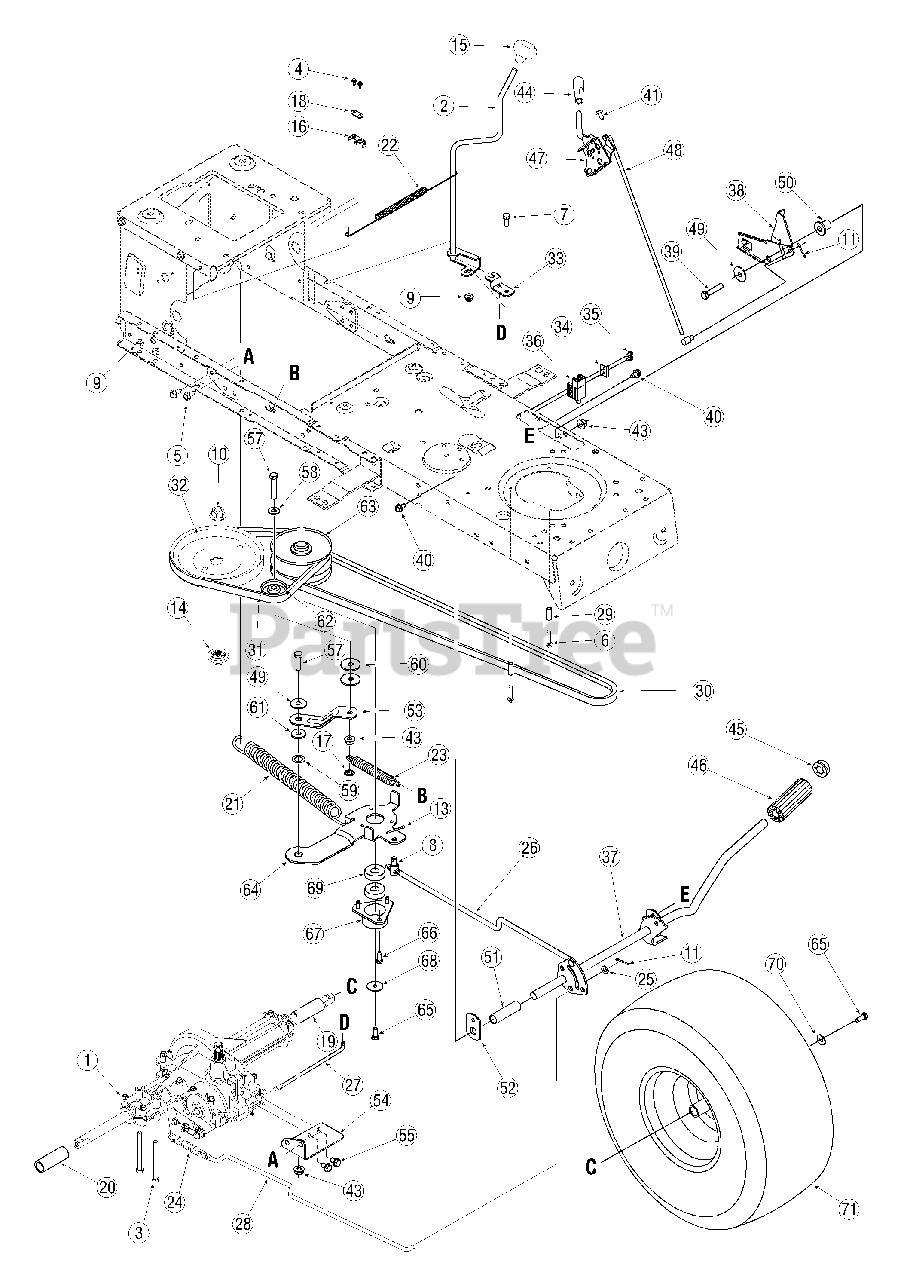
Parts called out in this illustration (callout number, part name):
1	Transmission Assembly
2	Lever Assembly, Shift
3	Screw, 5/16-18, 2.75, Gr5
4	Screw, #8-18, 0.500
5	Screw, 5/16-12, 0.750
6	Screw, 1/4-20, 1.250
7	Screw, 5/16-18, .75, Gr5
8	Ferrule, 3/8-24 x .375 Dia.
9	Nut, Flange Lock, 5/16-18, Gr F, Nylon
10	Nut, Flange, 9/16-18, Gr2
11	Pin, Cotter, 3/32, 1.0
12	Cotter Pin, Internal .125 Dia
13	Pin, Cotter, 1/8 x 1.25
14	Hub, Pulley, 5/8 Spline
15	Knob, Shift
16	Spring Switch, Short
17	Speed Nut, 3/8 (Push-on)
18	Plate, Insulator Nut
19	Sleeve, .758 x .821 x 3.3125
20	Sleeve, .758 x .821 x 2.4375
21	Spring, Extension, 1.15 OD x 7.90
22	Spring, Extension, .50 OD x 12.0
23	Spring, Extension, .78 OD x 3.5
24	Spring, Extension, .59 OD x 4.00
25	Washer, Flat, .330 x .630 x .0635
26	Control Rod, Variable Speed
27	Rod, Shift
28	Rod, Brake
29	Spacer, .260 x .372 x 1.030
30	Belt
31	Belt
32	Pulley, V-Type, 7.25 Dia
33	Shift Bracket, Adjustable
34	Plate, Switch
35	Screw, #10-16, 0.500
36	Switch, Interlock
39	Screw, 3/8-16, 1.75, Gr5
40	Screw, 5/16-18, 0.500
41	Screw, 1/4-20, 0.625
42	Adjustment Ferrule 1/4-20
43	Nut, Flange Lock, 3/8-16, Gr F, Nylon
44	Knob, Speed Control
45	Push Cap, 5/8
46	Pad, Foot, 4.0
47	Shift Lever, 7-Speed
48	Control Rod, Speed Selector
49	Spacer, Shoulder, .38 ID x 50 OD x.15
50	Spacer, Flange, .390 x .671 x .95
51	Spacer, .640 ID x .76 OD x 2.63
52	Support Bracket, Pedal
53	Bracket, Idler
54	Torque Bracket, Transmission
55	Screw, 5/16-18, 0.625
56	Screw, 3/8-16, 1.25, Gr5
57	Screw, 3/8-16, 2.00, Gr5
58	Washer, Flat, .406 x .875 x .059
59	Washer, Flat, .63 x 1.00 x .015
60	Washer, Flat, .406 x 1.5 x .105
61	Spacer, Shoulder, .625 ID x .169
62	Pulley, Flat Idler, 2.0 OD
63	Pulley Ass'y, Variable Speed, 4.75 OD
64	Bracket Ass'y, Variable Speed
65	Screw, 5/16-24, .750, Gr5
66	Screw, 1/4-20, 0.750
67	Cup, Bearing
68	Washer, Flat, .330 x 1.25 x .06
69	Bearing, Ball, 17 x 40 x 12
70	Bell Washer, .34 x .872 x .060
